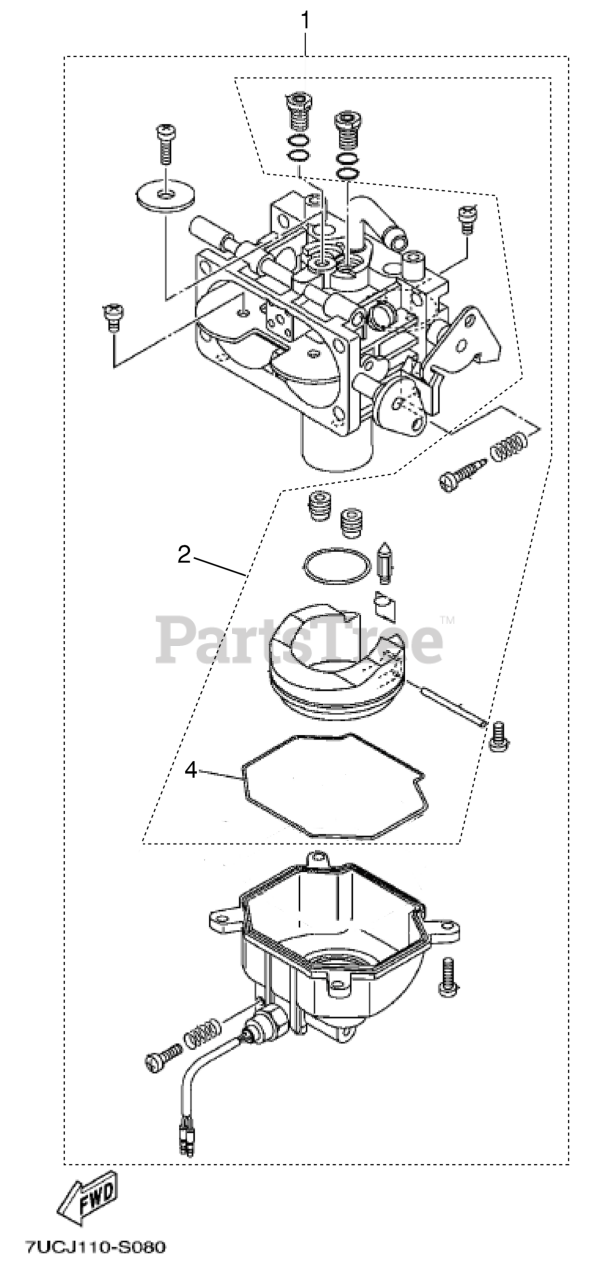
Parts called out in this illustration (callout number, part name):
1	CARBURETTOR ASSY 1 YAMAHA PN:
2	CARBURETTOR KIT
4	GASKET FLOAT CHAMBER YAMAHA PN
